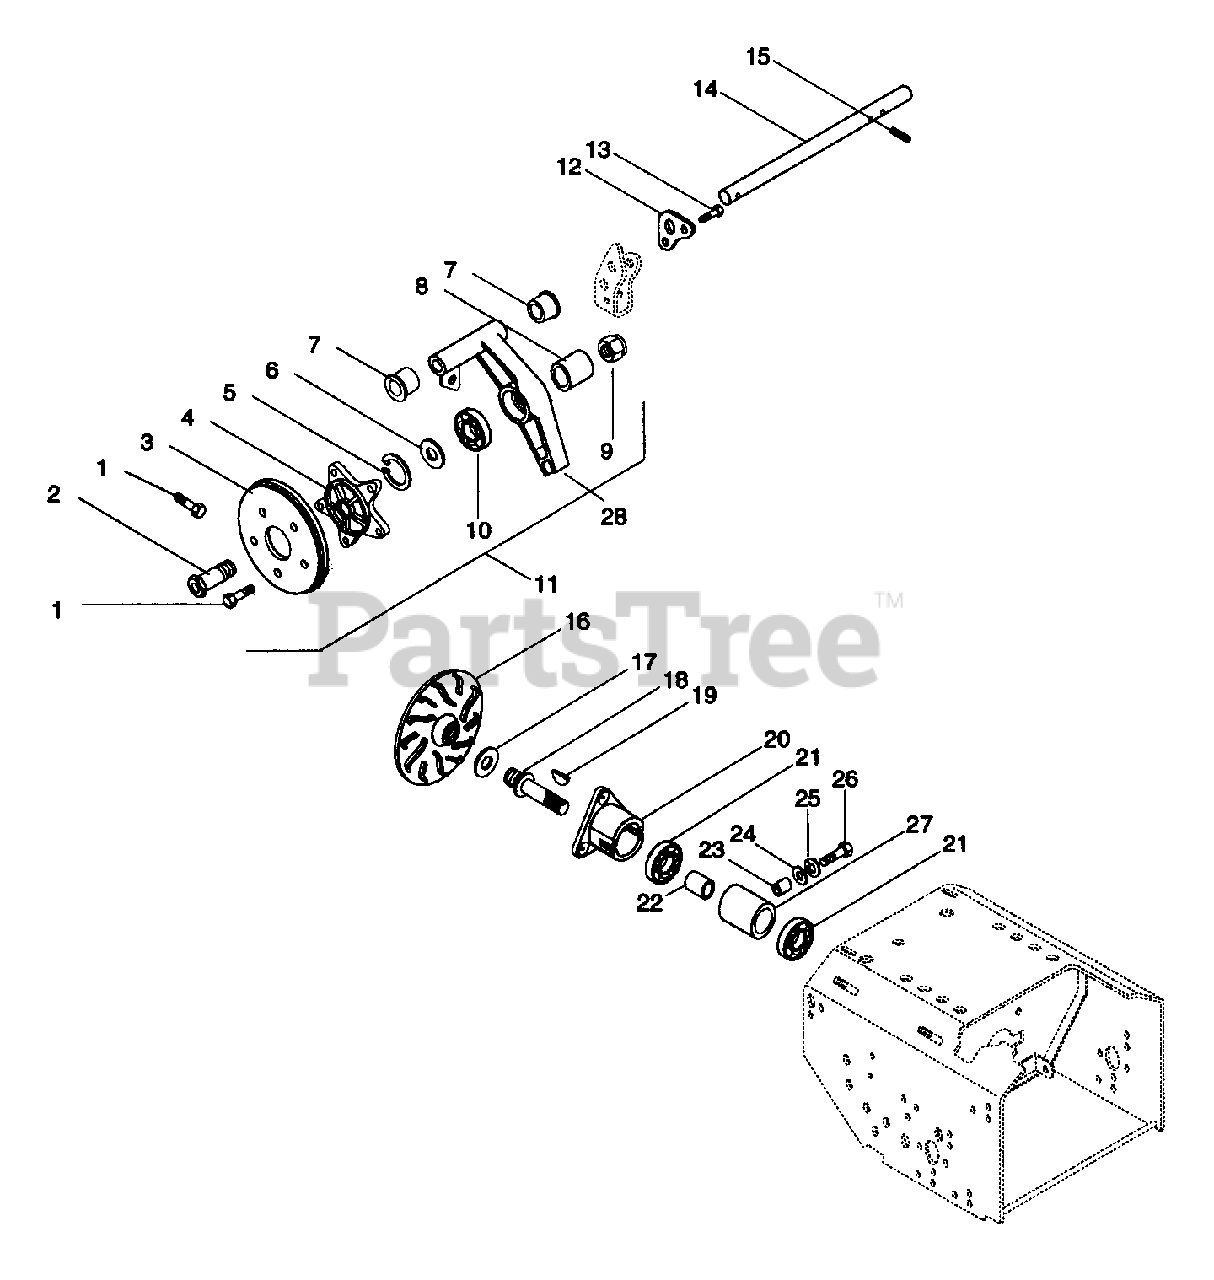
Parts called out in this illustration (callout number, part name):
1	SCR-TAP .312-18X.50 HWH PL TR
2	SPINDLE HUB
3	FRICTION DISC
4	DISC HUB
5	RG-RTNG-INT 1.750X.062
6	WSHR-FL-STL .880X1.250X.062
7	BSHG-FLG .625X.750X.500X.875BR
8	BSHG-SLV .882X1.250X.531
9	NUT-LK-NYL .875-14
10	BRG-BALL .876 X 1.750 X .50
11	FRICTION WHEEL ASSEMBLY
12	SUPPORT, SHAFT
13	SCR-TAP .250-20X.37 HWH PL TR
14	CARRIER SHAFT
15	PIN-ROLL .156X1.00
16	DRIVE PLATE
17	DRIVE DISC SPACER 1.3X.76X.19
18	SPINDLE
19	KEY-WDRF .125X.500X.203 SAE 3
20	HOUSING MOUNT
21	BRG-BALL .625X1.375X.44
22	BEARING SPACER
24	WSHR-FL-STL.344X.688X.065PL
25	WSHR-LK .312X.097 PL HVY
26	BLT-HEX .31-18X1.00 PL GR 2
27	SPINDLE HOUSING
28	CARRIER
